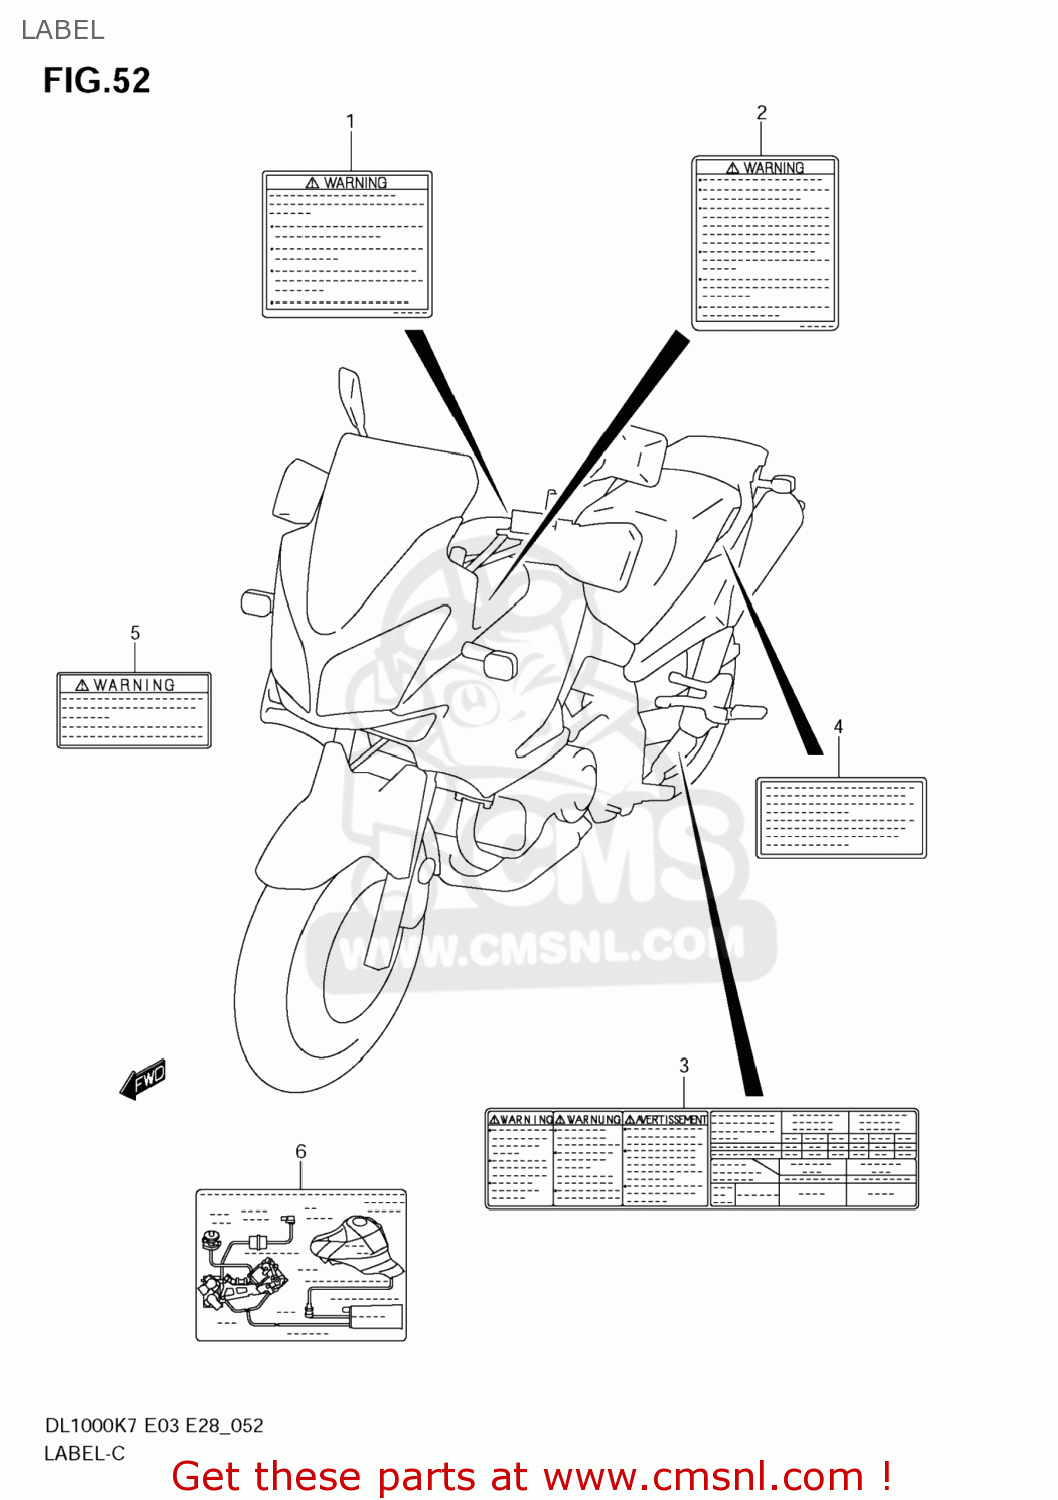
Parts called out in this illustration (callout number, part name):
1	LABEL,GENERAL WARNING
2	LABEL,SCREEN
3	LABEL,TIRE INFORMATION
4	LABEL,MANUAL NOTICE
5	LABEL,WARNING STEERING
6	LABEL,VACUUM HOSE ROUTING
7	MANUAL,OWNER'S
